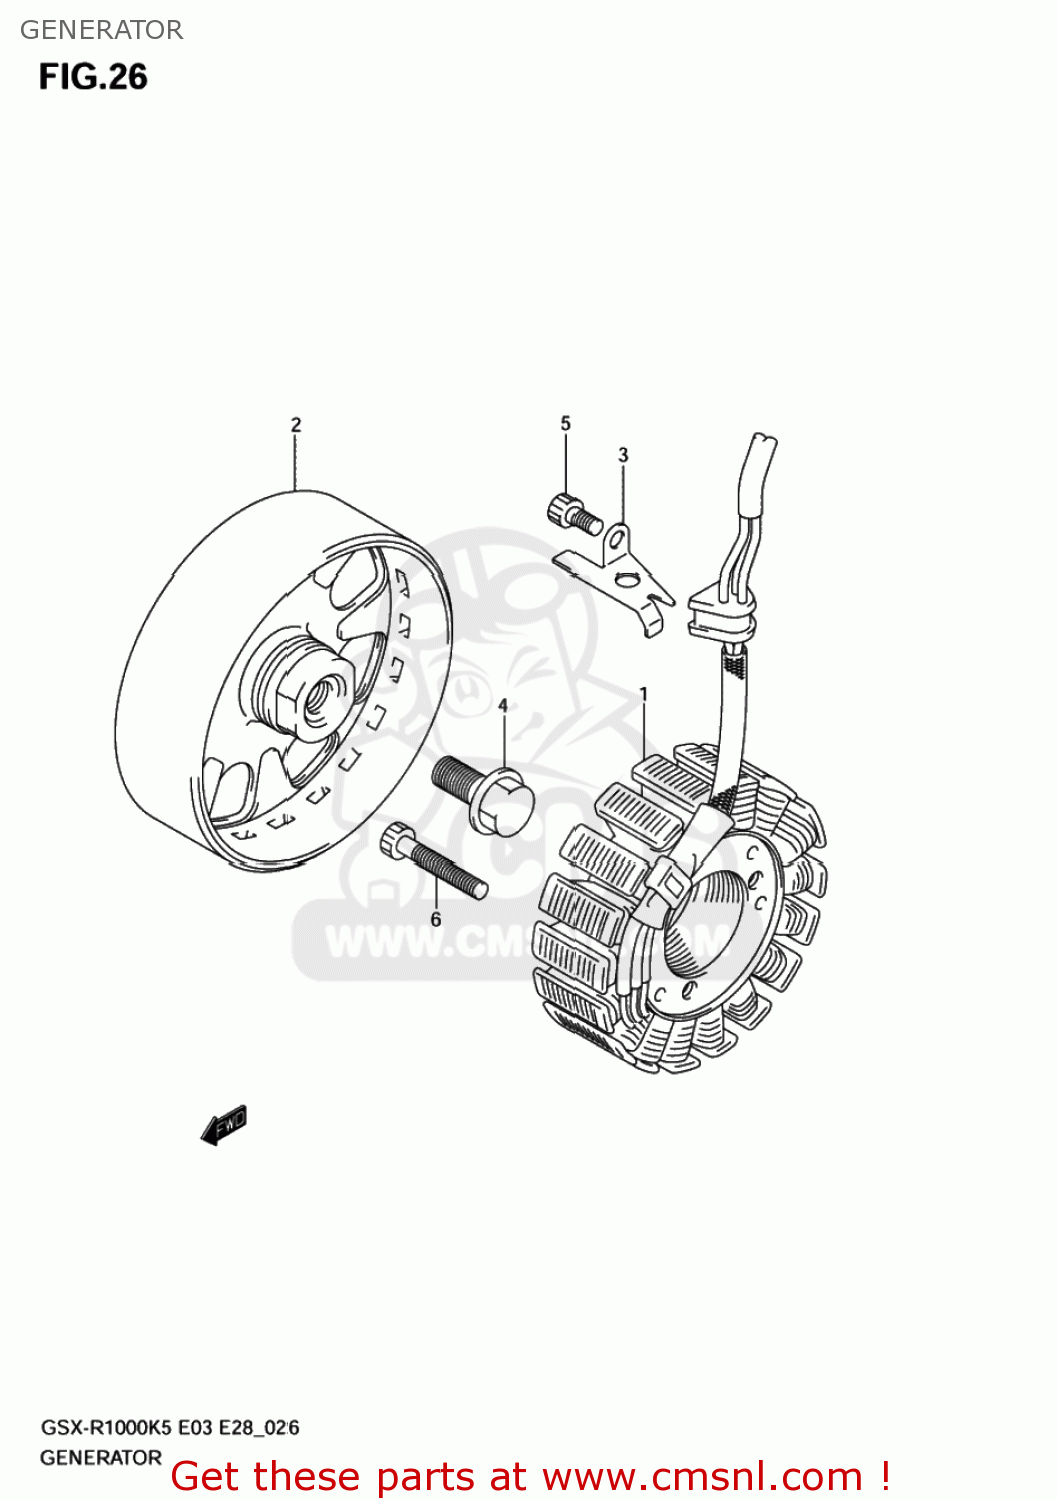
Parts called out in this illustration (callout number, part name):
1	STARTER ASSY
2	ROTOR ASSY
3	CLAMP,MAGNETO LEAD
4	BOLT(12X23)
5	BOLT,STRANGER
6	BOLT(6X30)
